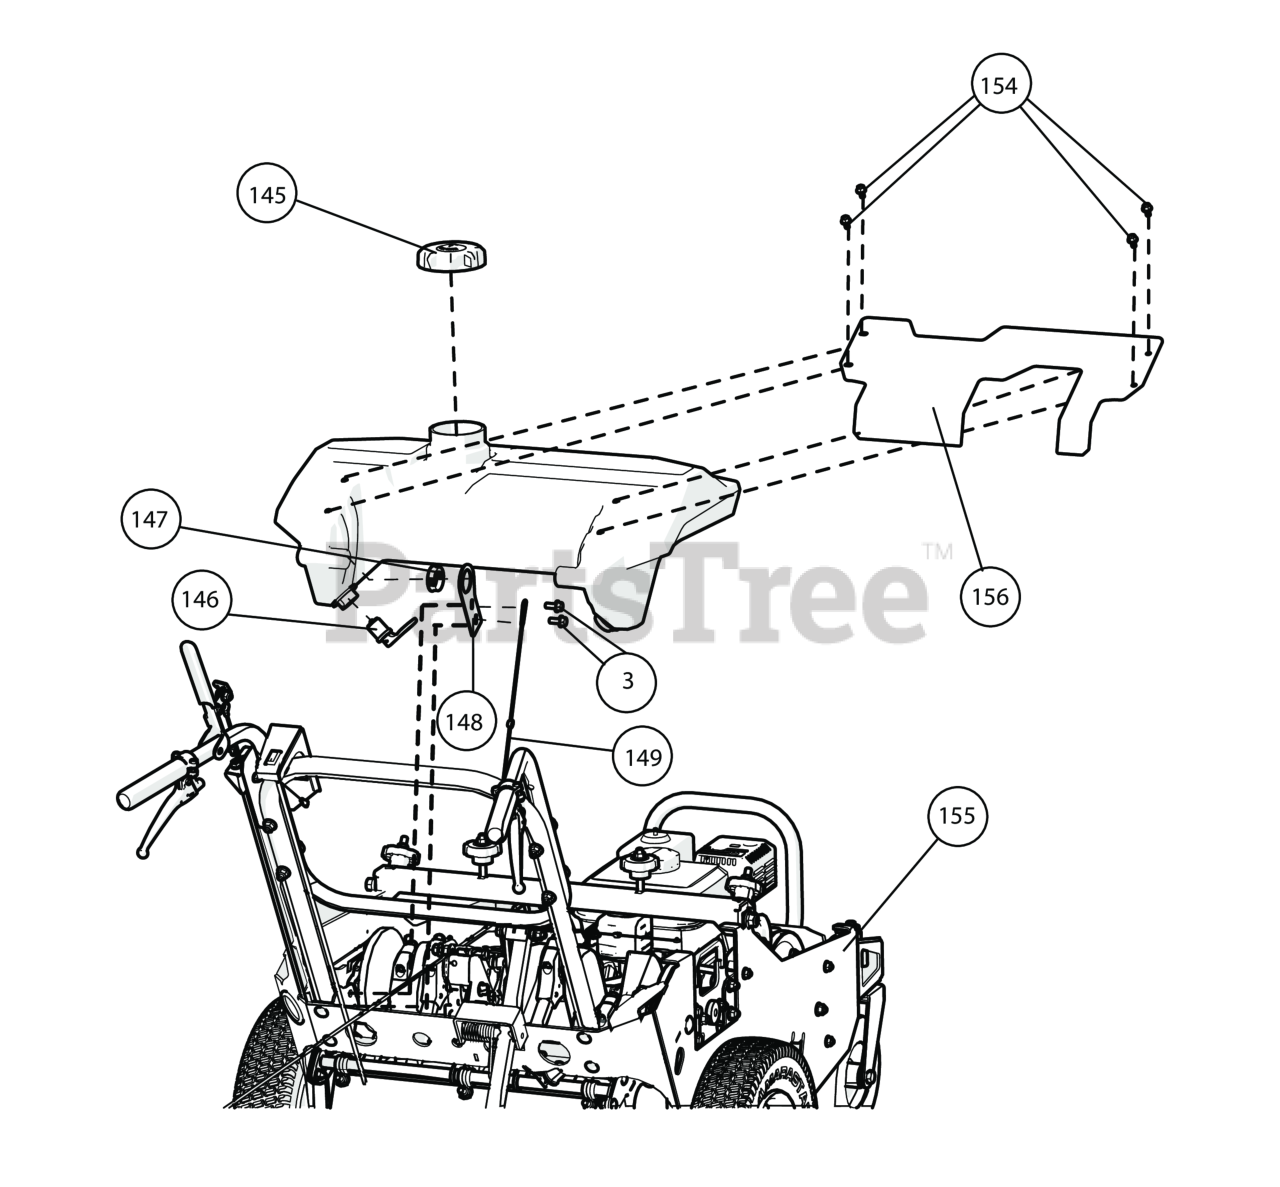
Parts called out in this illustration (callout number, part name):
3	SER HEX WASHER FLNG SCREW 5/16"-18 X 3/4"
144	TANK, WATER PL2501
145	CAP WATER TANK
146	PLUG DRAIN 1"
147	BUSHING, SNAP 1.31" ID
148	BRKT, PIVOT WATER TANK
149	LANYARD PLASTIC 10"
154	BOLT 1/4-20 X 1/2 SER FLANGE
155	ASM, PAINTED BODY W/DECALS & INSERTS
156	ASM, PAINTED COVER W/DECALS
